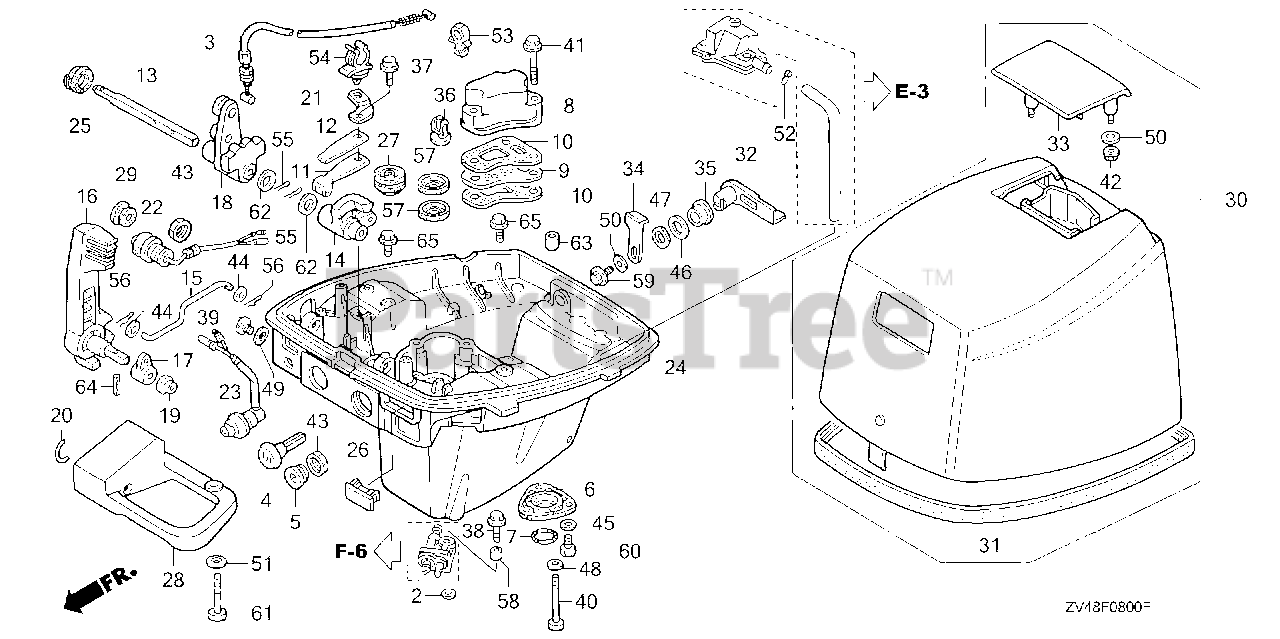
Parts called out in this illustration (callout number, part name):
2	WASHER, PIVOT
3	CABLE, NEUTRAL STARTING
4	KNOB, CHOKE
5	GUIDE, CHOKE KNOB
6	PLATE, EX.
7	BAND, EX. SEAL
8	COVER, EX. CHAMBER *NH8* (DARK GRAY)
9	PLATE, EX. CHAMBER
10	GASKET, EX. CHAMBER
11	SPRING, CLICK
12	SPRING, CLICK ASSIST
13	SHAFT, SHIFT
14	ARM, SHIFT
16	LEVER, SHIFT
17	LINK A, SHIFT
18	LINK, SHIFT (B)
19	BUSH, SHAFT
20	RUBBER, SHIFT SHAFT
21	BRACKET, WIRE HARNESS CLIP
23	LAMP ASSY., INDICATOR
24	CASE, OIL *NH282MU* (OYSTER SILVER METALLIC-U)
25	GROMMET, OIL CASE (B)
26	GROMMET, OIL CASE (D)
27	GROMMET, OIL CASE (E)
28	HANDLE, CARRYING *NH282MU* (OYSTER SILVER METALLIC-U)
29	GROMMET, CARRYING HANDLE
30	COVER, ENGINE *NH282MU* (OYSTER SILVER METALLIC-U)
31	SEAL, ENGINE COVER
32	LEVER, COVER LOCK *NH282MU* (OYSTER SILVER METALLIC-U)
33	HANDLE, TILT
34	HOOK, COVER LOCK
35	BUSH, COVER LOCK
36	GROMMET, WATER CHECK
37	BOLT, FLANGE (6X14)
38	BOLT, FLANGE (6X20)
39	BOLT, OIL CHECK (8X8)
40	BOLT, HEX. (6X40)
41	BOLT, FLANGE (6X35)
43	NUT, HEX. (16MM)
44	WASHER, PLAIN (5MM)
45	WASHER, PLAIN (6MM)
46	WASHER (14MM)
47	WASHER, WAVE (14MM)
48	WASHER, PLAIN (6MM)
49	WASHER, NYLON (8MM)
50	WASHER (6MM)
51	WASHER, PLAIN (8MM)
52	CLIP, TUBE (B12.5)
53	CLIP, ENGINE STOP SWITCH CORD
54	CLIP, WIRE HARNESS
55	PIN, SPLIT (2.0)
56	PIN, LOCK (5MM)
57	SEAL, WATER (14X26X6)
58	COLLAR, DISTANCE (6MM)
59	BOLT, HEX. (6X16)
60	BOLT, HEX. (6X16)
61	BOLT, HEX. (8X30)
62	WASHER, SHIFT
63	PIN, DOWEL (8X14)
64	PIN, SPRING (4X20)
65	BOLT, FLANGE (6X16)
